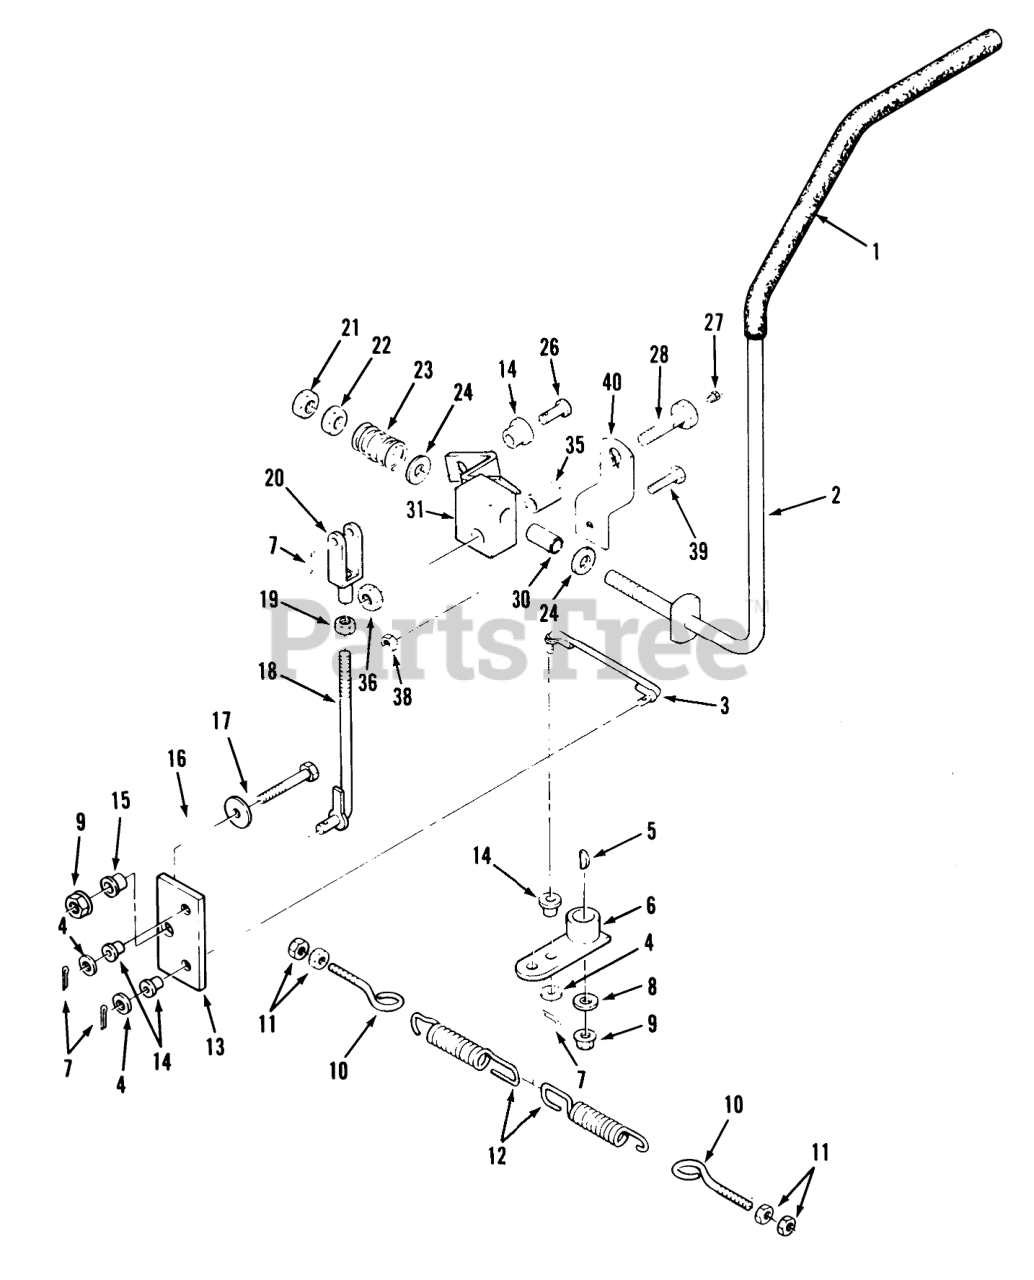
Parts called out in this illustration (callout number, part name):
1	Grip
2	WLDMT-STEER LVR LH B
3	ROD-STEERING R.H.
4	WASHER 5/16 SAE
5	KEY WOODR 1/8X1/2 DI
6	Arm-Hydro Control
8	Washer
9	NUT
10	EYE BOLT 1/4-20
11	Nut
12	SPG-NEUTRAL 20217-35
13	PLATE-STEERING PI B
14	BUSHING-FLANGED
15	SPACER-LIFT LINK
16	WASHER
17	BOLT
18	ASS'Y-ROD
19	Nut-Lock
20	CLEVIS
21	Jam Nut
22	Eslok Nut
23	SPRING
24	Washer
26	Pin-Clevis
27	Zerk
28	Bolt-Shoulder (Incl. Item #27)
30	BUSHING-STR LVR PVT
31	Steering Lever LH
35	BUSHING
36	Nut
38	Nut
39	Bolt
40	STRAP-PIVOT B
